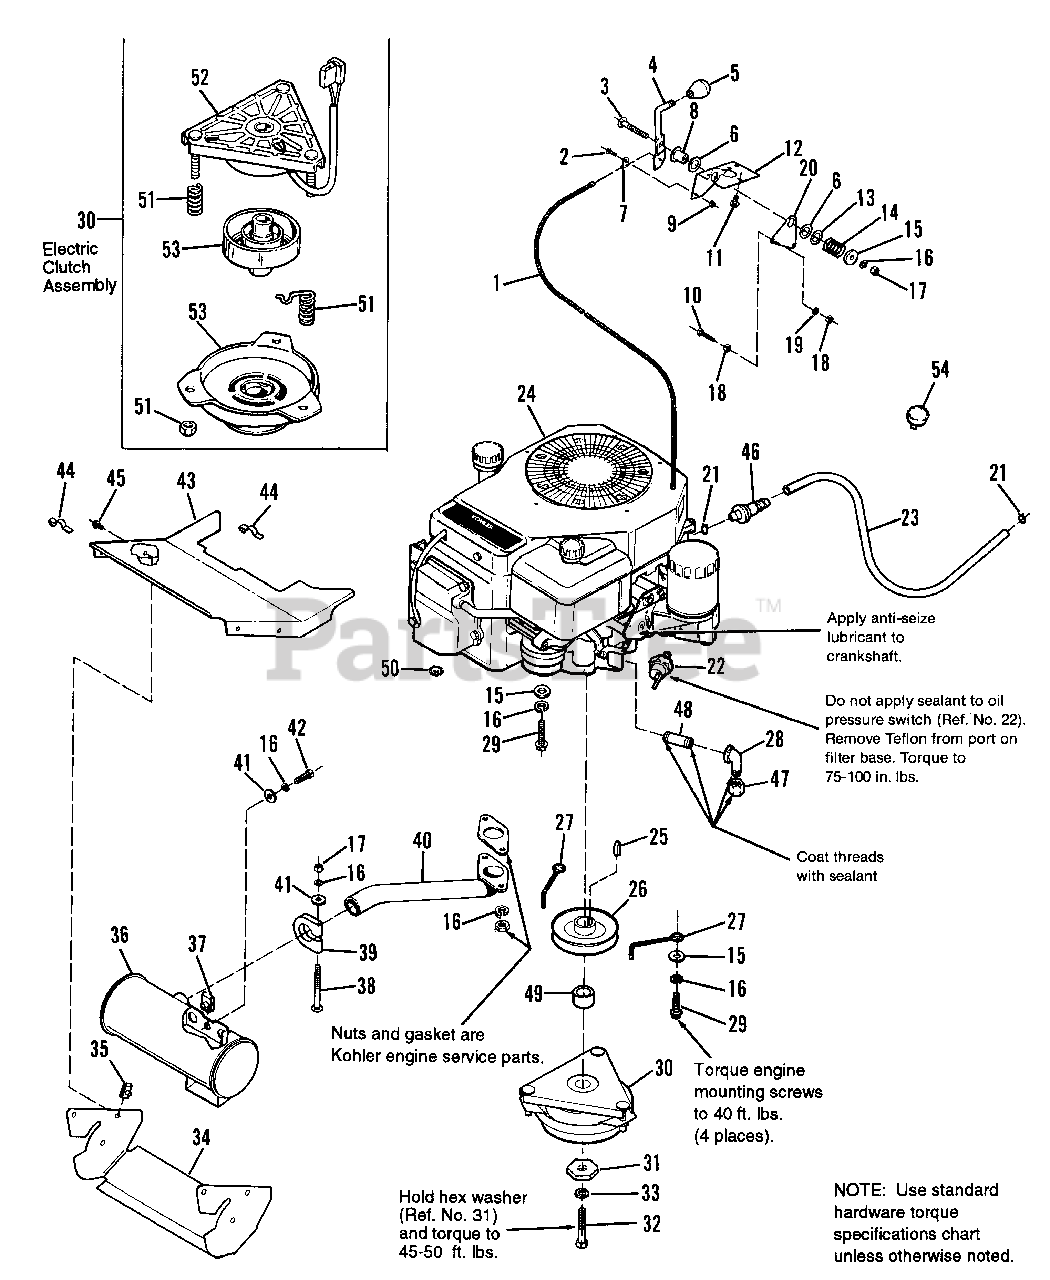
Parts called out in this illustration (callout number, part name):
1	CABLE, Throttle
2	SCREW, Trusshead, 10-32 x 1/2
3	CARRIAGE BOLT, 5/16-18 x 1-3/4
4	HANDLE, Throttle (Incl. Ref. No. 5)
5	KNOB, Throttle
6	WASHER, Nylon
7	CLIP, Bowden Wire
9	NUT ASSY., 10-32
10	CAPSCREW, Hex Hd., 1/4-20 x 1-1/4
11	SCREW, Plastite, 1/4-20 x 5/8
12	BRACKET, Throttle Mounting
15	WASHER, Plain, 5/16
16	LOCKWASHER, 5/16
17	NUT, Hex, Full, 5/16-18
18	NUT, Hex, Full, 1/4-20
19	LOCKWASHER, 1/4
20	PLATE, Spring
21	CLAMP, Hose
22	SWITCH, Oil Pressure
23	HOSE, Fuel, 45-1/2" Long
24	ENGINE, 14 HP Kohler
25	KEY, Hi-Pro
26	PULLEY ASSY.
28	STREET ELBOW, 3/8 Pipe
29	SCREW, Taptite, M8-1-1/4 x 30 mm
30	ELECTRIC CLUTCH (Incl. Ref. Nos. 51-53)
31	WASHER, Hex
32	CAPSCREW, Hex Hd., M10-1-1/2 x 95 mm
33	LOCKWASHER, 7/16
34	DUCT, Lower Muffler
35	NUT, Pal, 1/4-20
36	MUFFLER ASSY.
37	NUT, Pal, 5/16-18
38	CARRIAGE BOLT, 5/16-18 x 2-3/4
39	CLAMP, Muffler
40	PIPE, Exhaust
41	WASHER, Plain, 5/16
42	CAPSCREW, Hex Hd., 5/16-18 x 1
43	DUCT, Top, Muffler
44	CLIP
45	SCREW, Flange Whiz, 1/4-20 x 5/8
46	FUEL FILTER
48	PIPE NIPPLE, 3/8 x 2
50	LOCKWASHER, External Tooth
51	SPRING & NUT KIT
52	FIELD ASSY., Clutch
53	ROTOR ASSY./ARMATURE KIT
54	FASTENER, Panel
